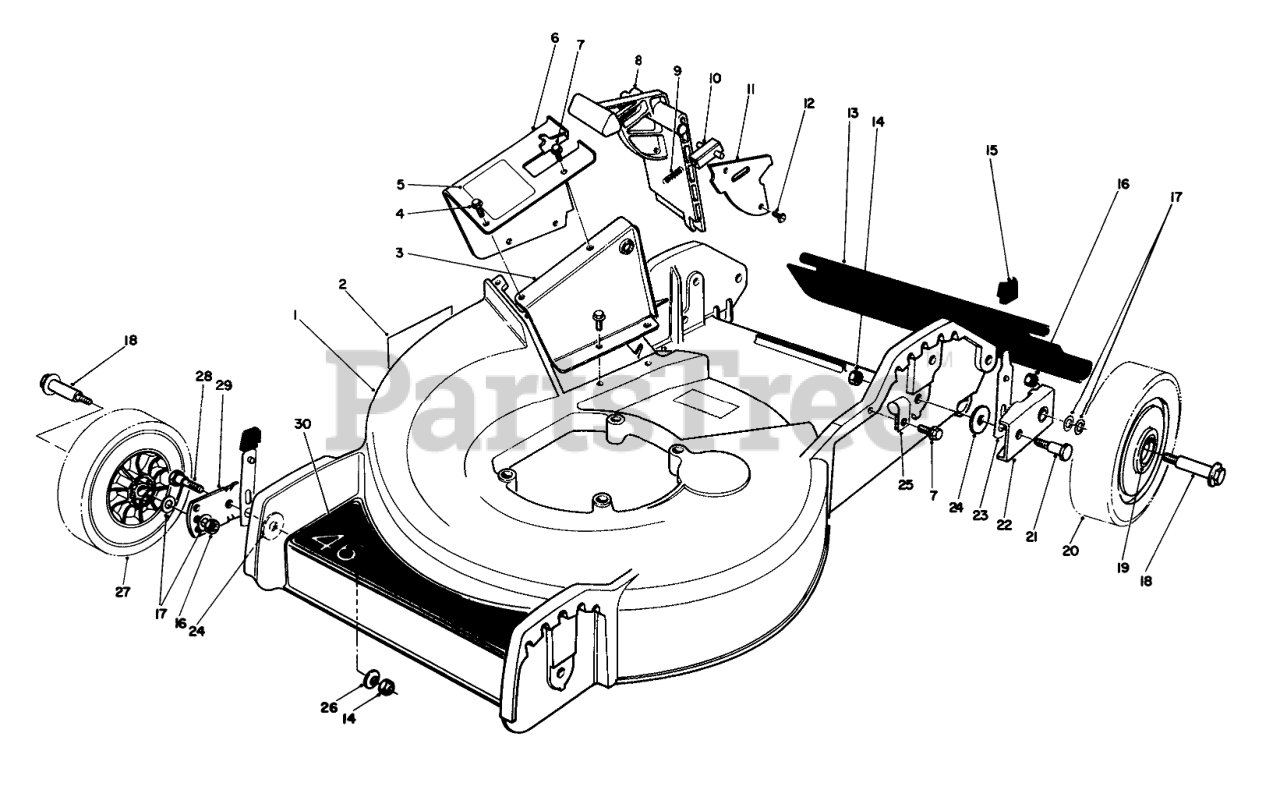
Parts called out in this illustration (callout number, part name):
1	HSG & CARTON
2	Decal Danger
3	Tunnel-Inner
4	SCREW
5	DECAL - DANGER
6	Tunnel-Outer (Incl. Ref #5)
7	SCREW
8	Door Mulching
9	SPRING-COMPRESSION, LATCH
10	Door Latch
11	Cover Door
13	SHIELD - TRAILING
14	NUT-LOCK, NI
15	KNOB-ARM
16	Nut
17	WASHER
18	BOLT-WHEEL
19	BUSHING
20	Wheel & Tire Assembly (Incl. Ref #19)
21	PIVOT SCREW
22	PIVOT ARM ASM
23	SPRING ARM ASM
24	PIVOT WASHER
25	CLAMP-NYLON
26	WASHER-BELLEVILLE
27	Wheel & Tire Assembly (Incl. Ref #19)
28	5/16-18 PIVOT SCREW
29	PIVOT ARM ASSY
30	DECAL - DECK
